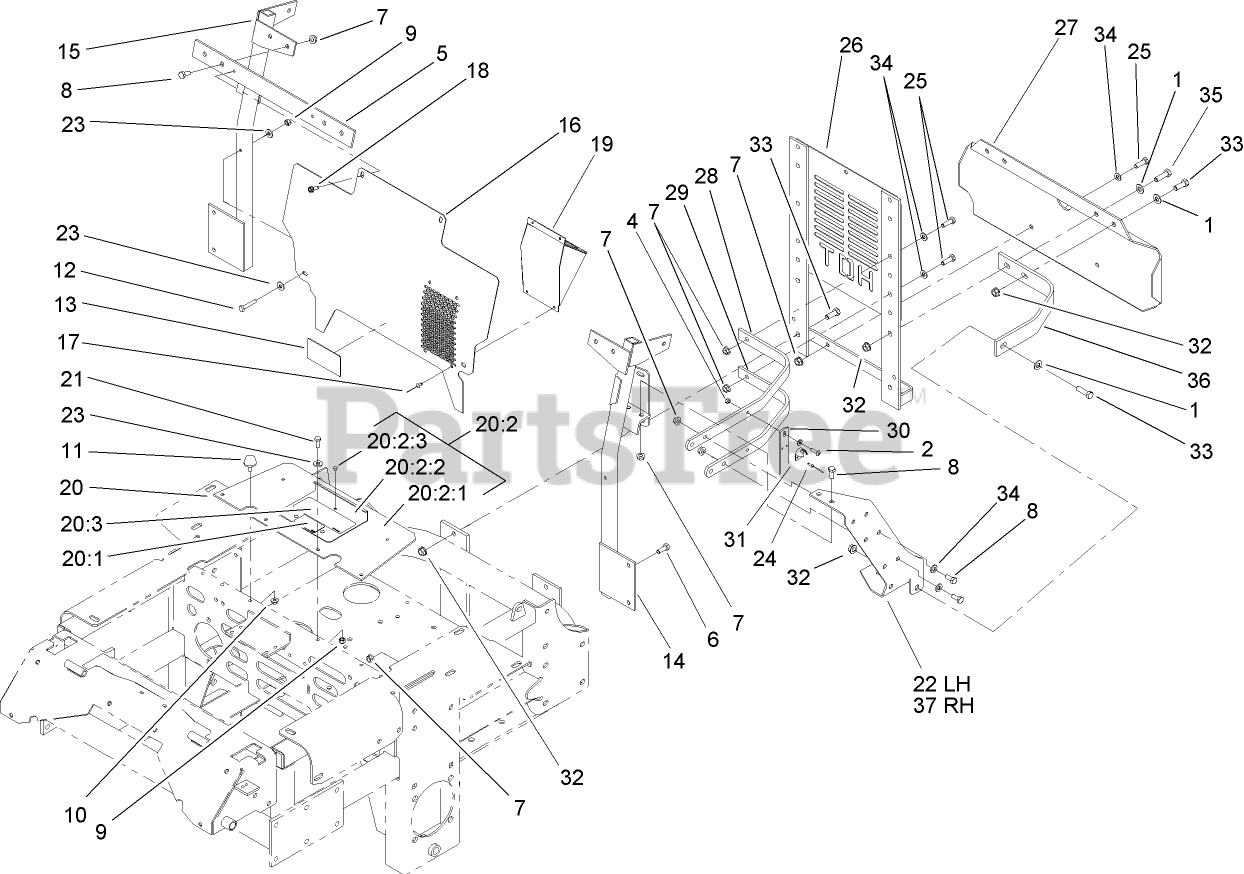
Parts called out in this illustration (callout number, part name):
1	WASHER-FLAT
2	SCREW-HEAD, TRUSS
4	NUT-LOCK, NI
5	CROSSBAR
6	SCREW-HH
7	NUT-HF
8	SCREW-HH
9	NUT-LOCK, NI
10	NUT-HF
11	BUMPER-RUBBER
12	SCREW-HH
13	DECAL-ROUTING, BELT
14	Brace-Radiator, LH
15	BRACE-RADIATOR, RH
16	Deflector-Air
17	RIVET-POP
18	SCREW-HWHTF
19	Plenum-Intake, Air
20	SHIELD ASM
20:1	DECAL-IMPORTANT
20:2	SHIELD AND LIFT ASM
20:2:1	SHIELD-ENGINE
20:2:2	LIFT-SHIELD
20:2:3	RIVET-POP
20:3	DECAL-DEVICES, ROTATING
21	SCREW-HH
22	PLATE-SIDE, LH
23	WASHER-FLAT
24	RIVET
25	SCREW-HH
26	MOUNT-RADIATOR, REAR
27	GUARD-BUMPER
29	RIB-BOTTOM
30	BAR-HOOK, LATCH
31	KEEPER-LATCH, RUBBER
32	NUT-HHF, WHIZ
33	SCREW-HH
34	WASHER-PLAIN
35	SCREW-HH
36	STRAP-GUARD
37	PLATE-SIDE, RH
